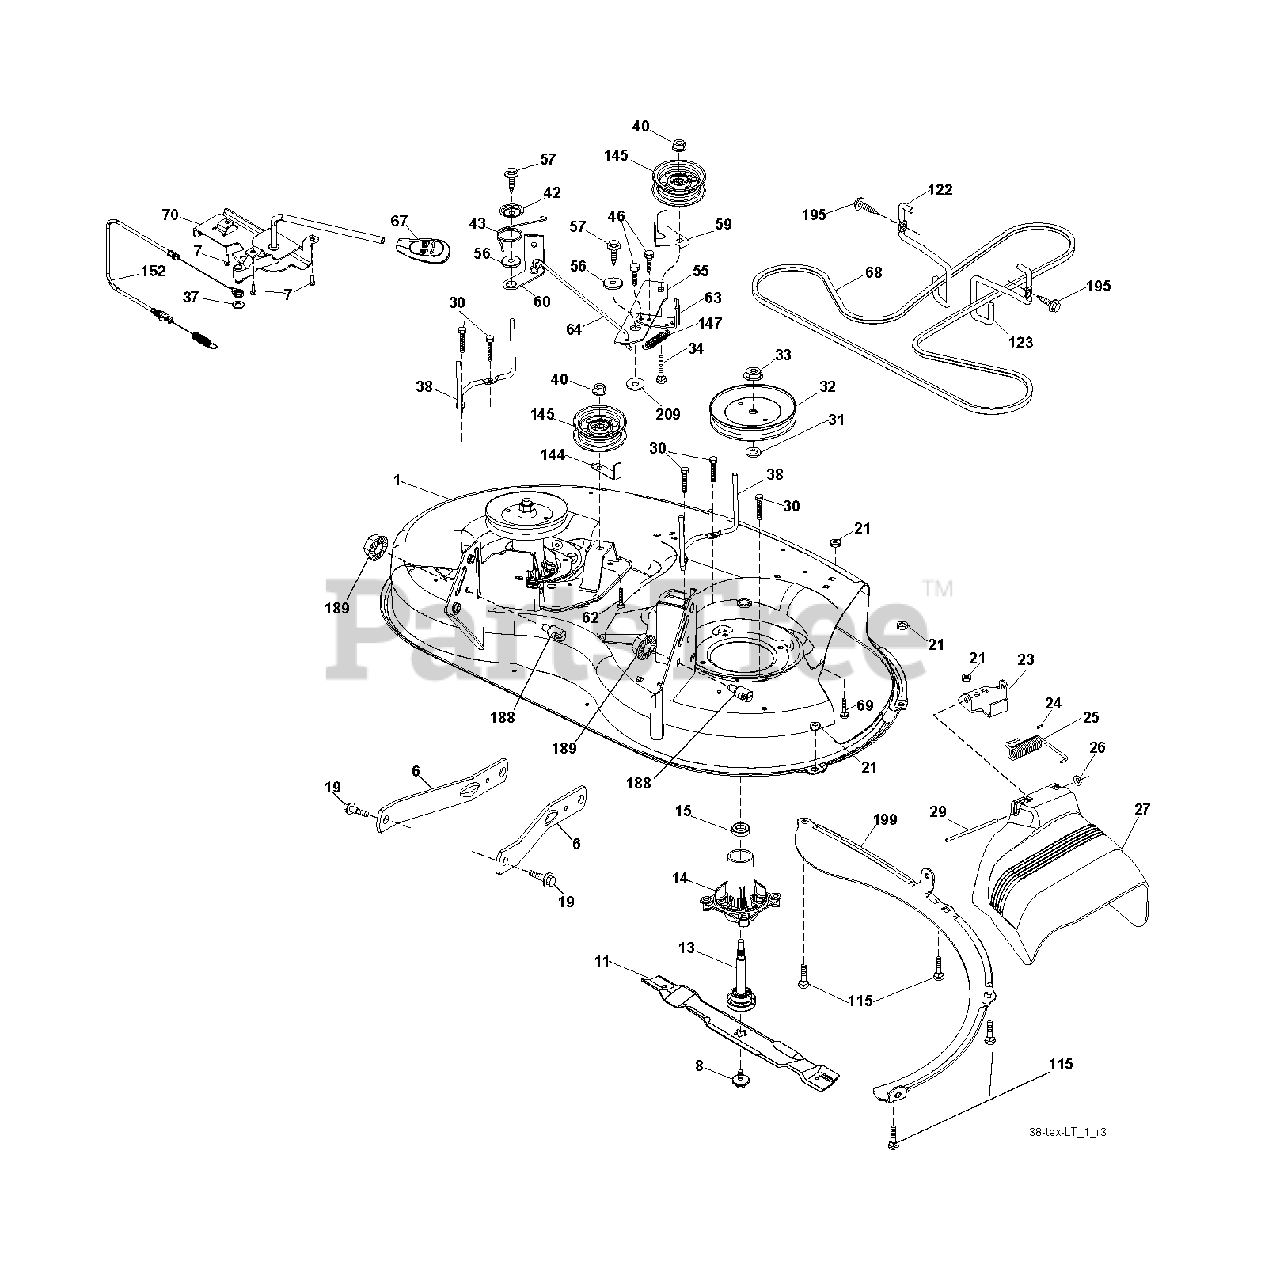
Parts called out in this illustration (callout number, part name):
6	ARM.SUSPENSION.MOWER.R
7	SCREW.#10 X 0.750.BOS THREAD
8	BOLT.WASHER.ASM.7/16-2
11	BLADE 38" PREMIUM
13	SHAFT.ASM.MDRL.N/GREASE.38
14	HOUSING MANDREL
19	BOLT.SHOULDER
21	LOCKNUT
23	BRKT.DEFLECTOR.38"2005+
24	CAP-SLEEVE LT
25	SPRING.TORSION.DEFLECT
26	NUT PUSH M
29	ROD.HINGE
30	SCREW, WASHER HEAD
31	WASHER.SPACER.MANDREL
32	PULLEY.MANDREL.5.0.PD.38"
33	NUT.FLANGE.LOCK.TOP
34	BOLT.3/8-16X1.50
38	KEEPER BELT LH MANDREL
40	NUT LOCK FLG 3/8-16 UNC
42	SPRING.TORSION.BRAKE
43	SRPING.TORSION.RETAINE
46	SCREW.1/4-20X5/8
55	IDLER.ARM
56	SPACER.RETAINER
57	SCREW 3/8-16X1
59	GUARD, BELT
60	ARM BRAKE MOWER RH 38"
62	BOLT.3/8-16X1.50
63	ARM BRAKE MOWER RH
64	LINK BRAKE
67	HANDLE.CLUTCH.CABLE.LT
69	BOLT
70	CLUTCH.ASM.MANUAL.LT.TEX
115	BOLT
122	KEEPER BELT ENGINE LH
123	KEEPER BELT RH
144	KEEPER, BELT IDLER
145	PULLEY.IDLER.48"PRIMARY
147	SPRING RETURN
149	SPRING.RETAINER.YELLOW.ZINC
152	CLUTCH CABLE
188	STUD.FASTNER.W/ANTI-ROTATE
189	NUT LOCK HEX FLANGE 5/16-18
195	SCREW, 3/8-16X3/4
199	BAFFLE VORTEX
209	WASHER 12/32X2X10GA
